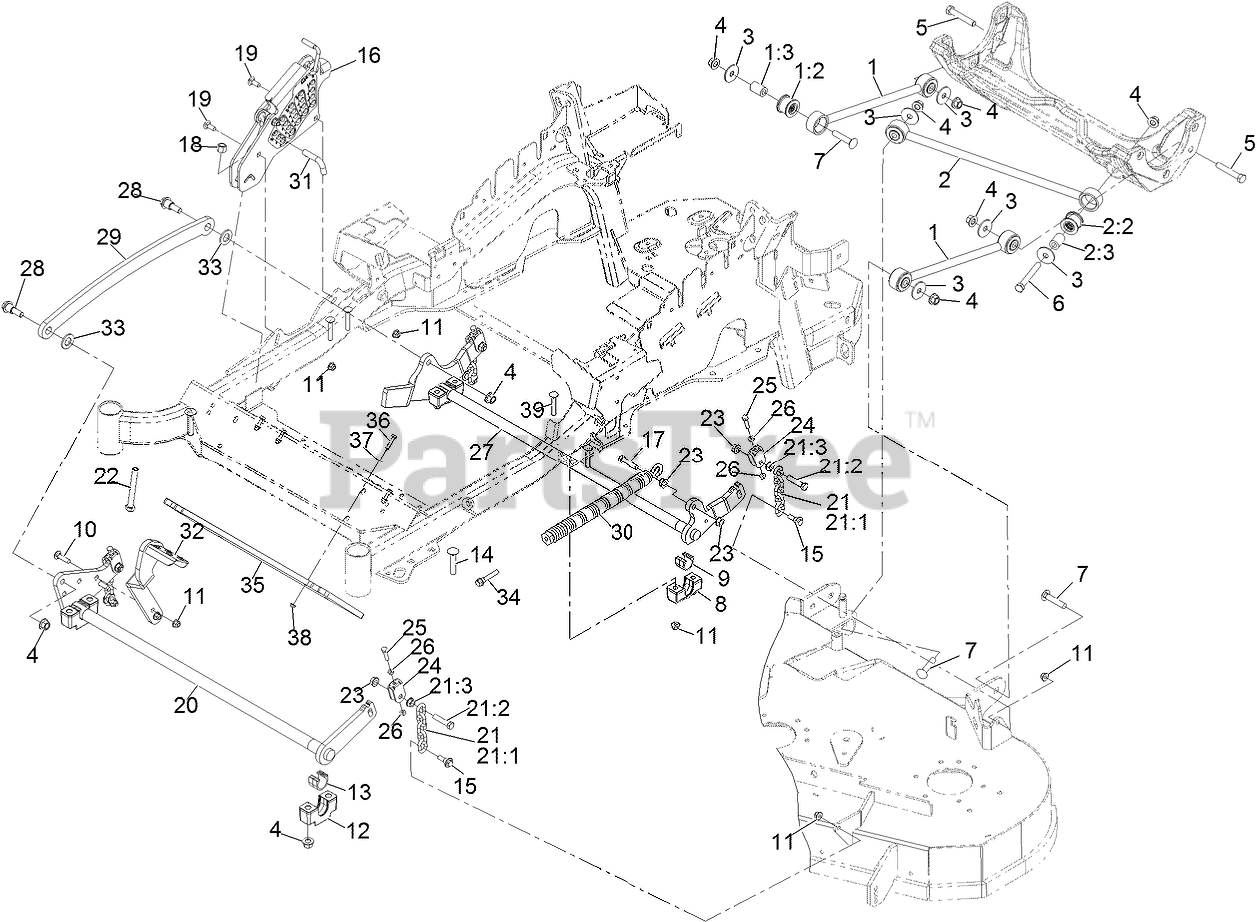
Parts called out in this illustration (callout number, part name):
1	DECK STRUT ASM
1:2	BUSHING-SUSPENSION, RUBBER
2	PANHARD ROD ASM
2:2	BUSHING-SUSPENSION, RUBBER
3	WASHER-THRUST
4	Nut-Lock 1/2-13
5	SCREW-HH
6	SCREW-HH
7	SCREW-CARR
8	SUPPORT-CROSS SHAFT, BEARING REAR
9	BEARING-CROSS SHAFT, REAR
10	SCREW-CARR
11	NUT-HF, NI
12	SUPPORT-CROSS SHAFT, BEARING
13	BEARING-CROSS SHAFT, FRON
14	Bolt-Carriage 1/2-13 X 2 1/2 Spl Neck
15	SCREW-SHOULDER, HHF
16	HOC ASM
17	SCREW-HH
18	NUT-LOCK, NI
19	BOLT-CARR
20	DECKLIFT-FRONT
21	DECK LIFT CHAIN ASM
21:1	CHAIN-LIFT, DECK
21:2	SCREW-HH
22	BOLT-TAP
24	YOKE-ADJUST, DECK
25	SCREW-HH
26	NUT-JAM
27	LIFT-DECK, REAR
28	SCREW-SHOULDER, HHF 1/2-13 X 1.12
29	LINK-LIFT, DECK
30	SPRING-EXTENSION
31	PIN-HOC
32	LEVER-FOOT
33	WASHER-FLAT
34	BOLT-SHOULDER
35	WEIGHT-TOE BOARD
36	SCREW-HH
37	WASHER-FLAT
39	Bolt-Carriage 3/8-16 X 2 1/4
